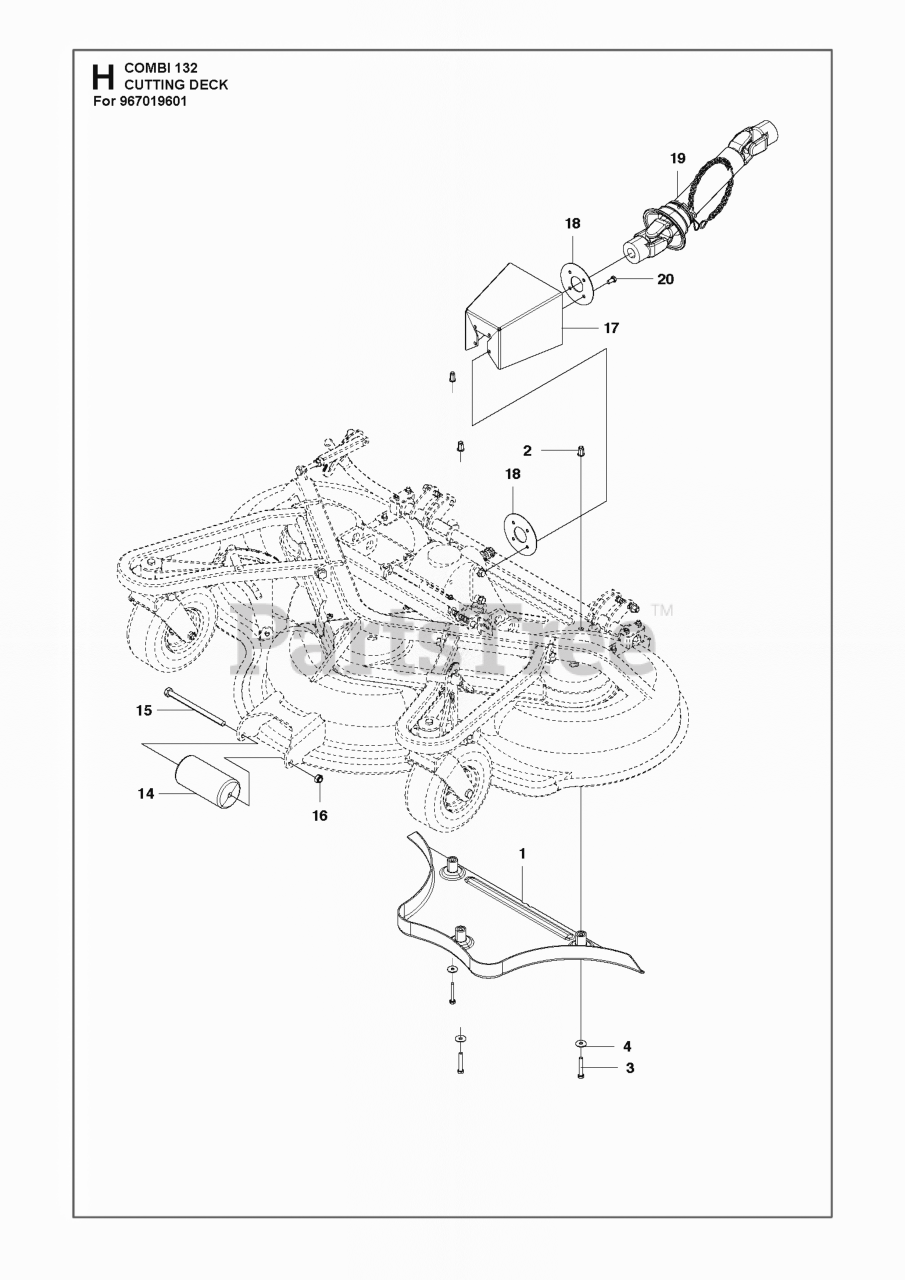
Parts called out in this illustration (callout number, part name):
2	BLIND RIVET NUT
14	ROLLER
20	BOLT - M8X16
